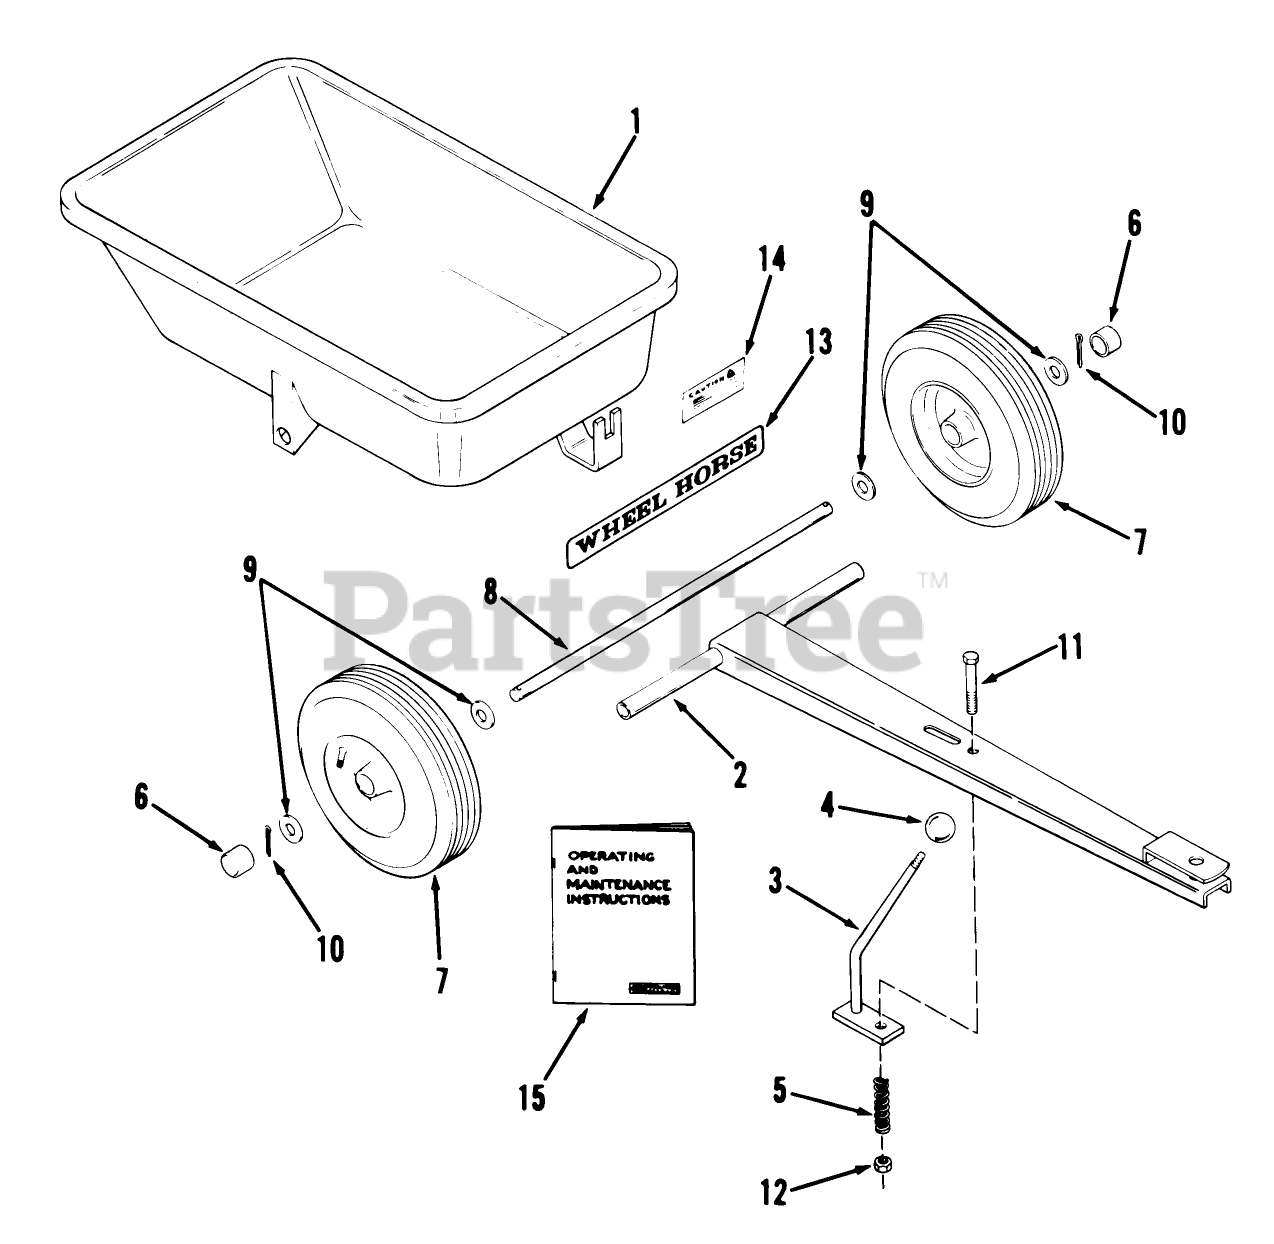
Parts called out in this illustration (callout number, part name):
1	Box Ass-y.
9	WASHER
15	MANUAL-OPERATOR
